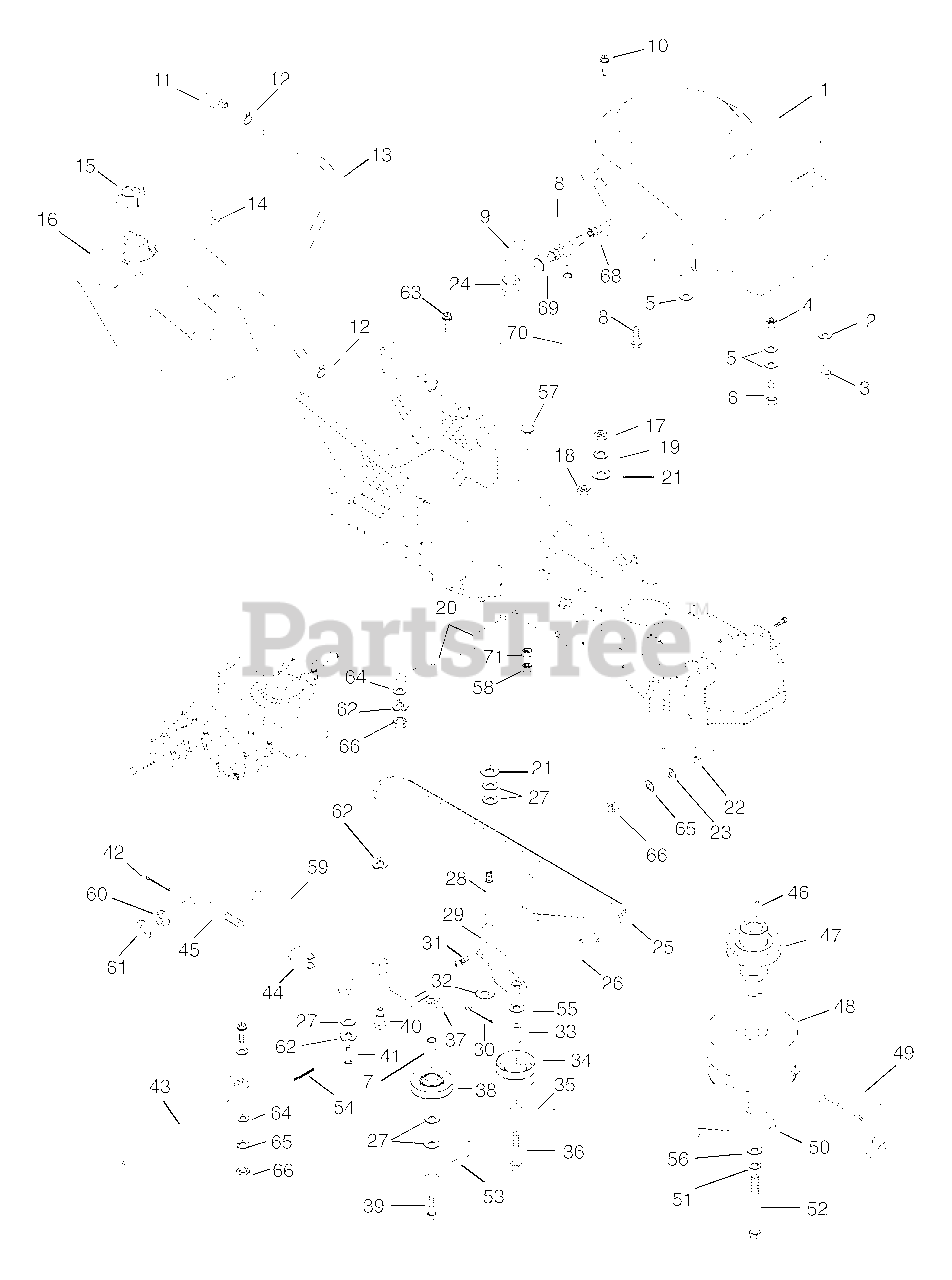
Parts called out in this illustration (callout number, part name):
1	ENGINE, B&S INTEK 18HP V TWIN
1	ENGINE, B&S INTEK 20HP V TWIN
1	ENGINE, B&S INTEK SINGLE 17HP
2	@WSHR-LK-EXT.391X.628X.036YWZC
3	@SCR-TAP .38-16X1.25 HWH TR YZ
4	@NUT-LK-CTR .31-18 YWZC
5	WSHR-FL-STL .328X.875X.062YWZC
6	@BLT-HEX .31-18X1.50 GR5 YWZC
7	TUBE, SPACER .380X.625X.69
8	NIPPLE
9	ELBOW .375-18 NPTF
10	@SCR-TAP .31-18X.75 HWH TR YWZ
11	TANK FITTING
12	CLAMP-HOSE WIR.490/.510X.092#8
13	HOSE- FUEL LINE 36.00"
13	HOSE- FUEL LINE 48.00"
14	BSHG-FLG .375 X 1.062 X .625 R
15	FUEL CAP
16	FUEL TANK
17	@NUT-HEX .38-16 YWZC
18	@NUT-LK-CTR .38-16 YWZC
19	@WSHR-LK .38X.094 REG YWZC
20	FINGER, BELT
21	@WSHR-FL-STL.438X1.00X.083 YWZ
22	BELT FINGER
23	@WSHR-FL-STL.312X.734X.065 YWZ
24	ADAPTER, OIL DRAIN
25	V-BELT, 4L-WRAPPED
26	SPRING, EXT
27	WSHR-FL-STL .390X.75X.125 YWZC
28	SHOULDER STUD
29	ARM - IDLER PIVOT
30	@PIN-CTR .18X1.25 EXTPRSQCT YZ
31	FTG-LUBE .25-28X.256 YWZC
32	WSHR-FL-STL .52X.827X.062 YWZC
33	SPACER, TUBE .38X.625X2.37
33	TUBE .380 X .625 X 1.620
34	IDLER-FLAT 3.25 X .38 NWHAMSHR
35	FINGER - BELT
36	@BLT-HEX .38-16X4.50 GR5 YWZC
36	@BLT-HEX .38-16X3.50 GR5 YWZC
37	IDLER PIVOT ARM
38	IDLER-V 3X.38
39	@BLT-HEX .38-16X1.75 GR5 YWZC
40	BLT-SHLDR .38-16X1.25
41	PIN-CLEV .312X.822 HDND PL
42	@PIN-CTR .09X.75 EXTPRSQCT YWZ
43	FINGER, BELT
44	YOKE, .312-24 X 2.25
46	KEY-SQ .25 X 1.25 X .25 SAE
47	SHEAVE EXT., SHAFT (HYDRO)
47	SHEAVE EXTENSION SHAFT- HYDRO
48	ELECTRIC CLUTCH/BRAKE (3.4AMP)
48	CLUTCH, ELECTRIC - WARNER
49	ANCHOR, CLUTCH
49	ANCHOR - CLUTCH
50	V-BELT, 4L-RAW EDGE
51	WSHR-LK .438X.133 HVY YWZC
52	BLT-HEX .44-20 X 5 GR5
52	BLT-HEX .44-20X4.00 GR5 YWZC
53	FINGER - BELT
54	PIN-HAIR INT .08X.18X1.18 YWZC
55	WSHR-FL-STL .390X.88X.18 YWZC
56	WSHR-FL-STL.463X1.375X.25 YWZC
57	BLT-RDHDSQNK .31-18X1.0 SHTYZ
58	@NUT-LK-CTR .31-18 YWZC
59	SG-TENS .105X.85X5.00 WLD 40
60	BSHG-FLG .320X.620X.312 NY
61	WSHR-FL-STL .505X.880X.072 YWZ
62	WAVE WASHER .531X.781X.125FH
63	BLT-RDHDSQSHK.31-18X.75 GR2 YW
64	@WSHR-FL-STL.344X.688X.065YWZC
65	WSHR-LK .312X.097 HVY YWZC
66	@NUT-HEX .31-18 YWZC
67	J-CLAMP
68	ADAPTER, OIL DRAIN
69	COCK, OIL DRAIN
70	TUBE OIL DRAIN
71	NUT-LK-NYL.312-18 PL
